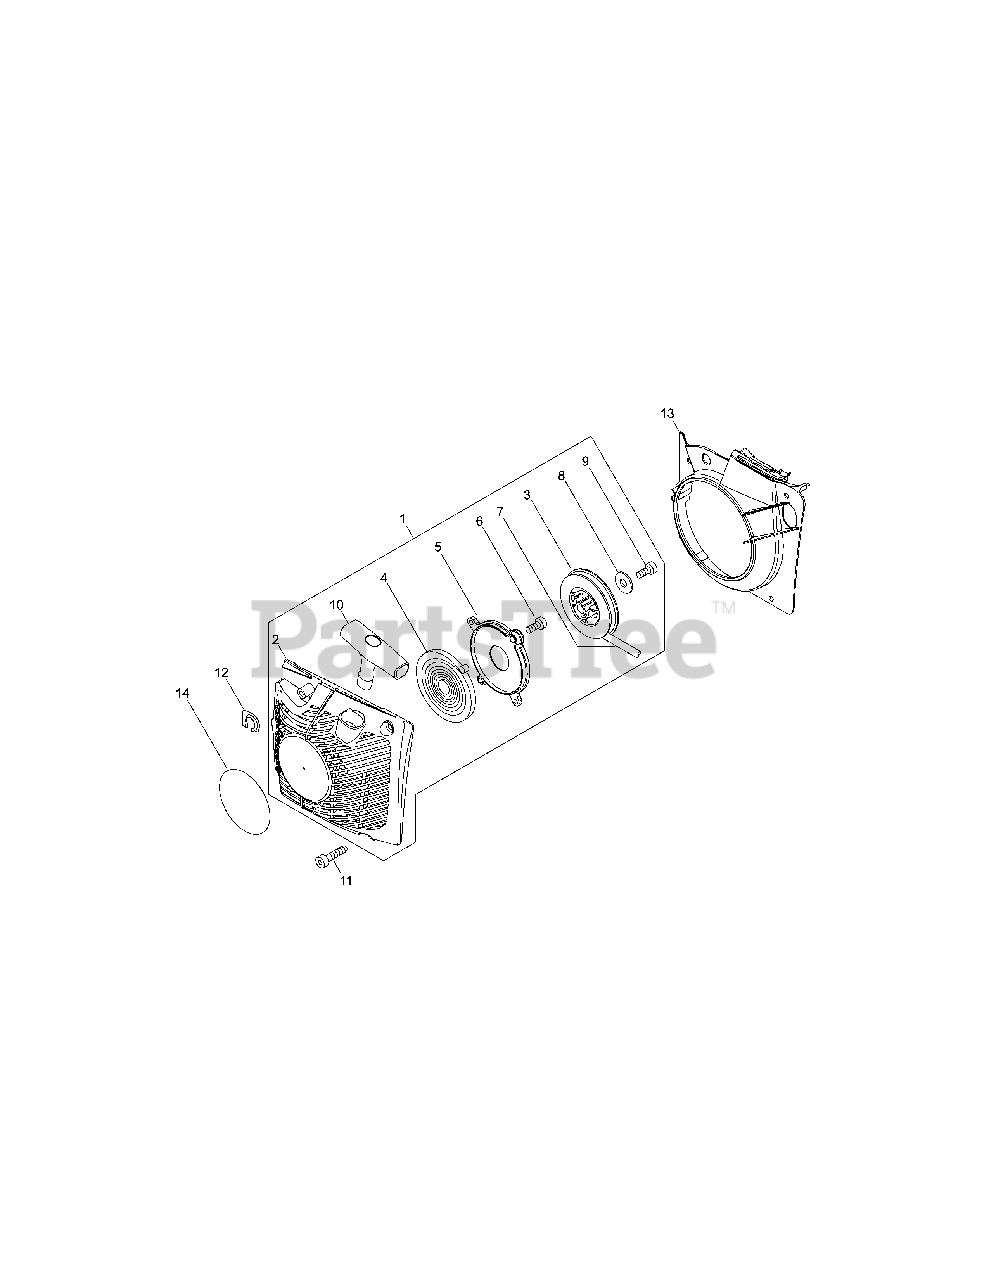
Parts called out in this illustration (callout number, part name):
1	STARTER ASY
2	STARTER CASE
3	REEL, ROPE
4	SPRING, REWIND
5	PLATE, STARTER
6	BOLT, TORX 4
9	BOLT, TORX 5
10	GRIP, STARTER
11	BOLT, TORX 5
12	PLATE,EYE
13	COVER,FAN
14	LABEL,ECHO
